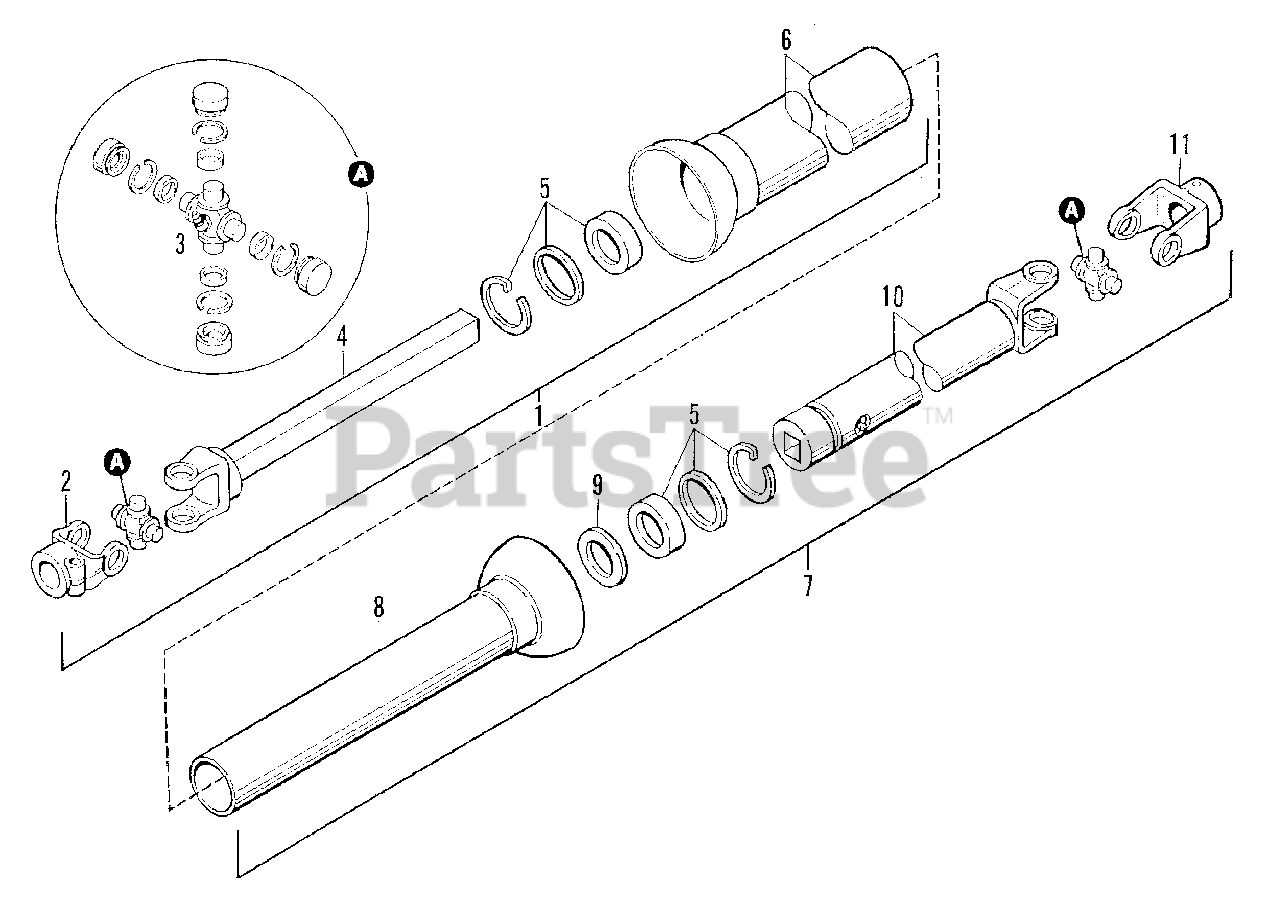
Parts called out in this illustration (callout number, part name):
1	PTO ASSEMBLY, Tractor End (Use 2018551 PTO Assembly)
1	PTO ASSEMBLY, Tractor End
2	YOKE (Tractor End)
3	U-JOINT KIT
3	FITTING, Lube, Special Shoft, 1/4 x 65 Degrees
4	SHAFT & YOKE ASSEMBLY
6	SHIELD, Outer (Use SHIELD 2108556)
6	SHIELD, Outer
7	PTO ASSEMBLY, Implement End (Use 2108608 PTO Assembly)
7	PTO ASSEMBLY, Implement End
8	SHIELD, Inner (Use SHIELD 2108557
8	SHIELD, Inner
9	BEARING, Nylon
10	TUBE & YOKE ASSEMBLY (Use TUBE & YOKE ASSEMBLY 2108559)
10	TUBE & YOKE ASSEMBLY
11	YOKE, Implement End (Service w/2108609 YOKE)
11	CAPSCREW, Socket Head, 5/16NC x 2-1/2, Gr.8
11	NUT, Lock, 5/16NC
11	YOKE, Implement End (Type l)
11	YOKE, Implement End (Type ll)
11	CAPSCREW, Socket Head, 3/8NC x 2, Gr. 8
